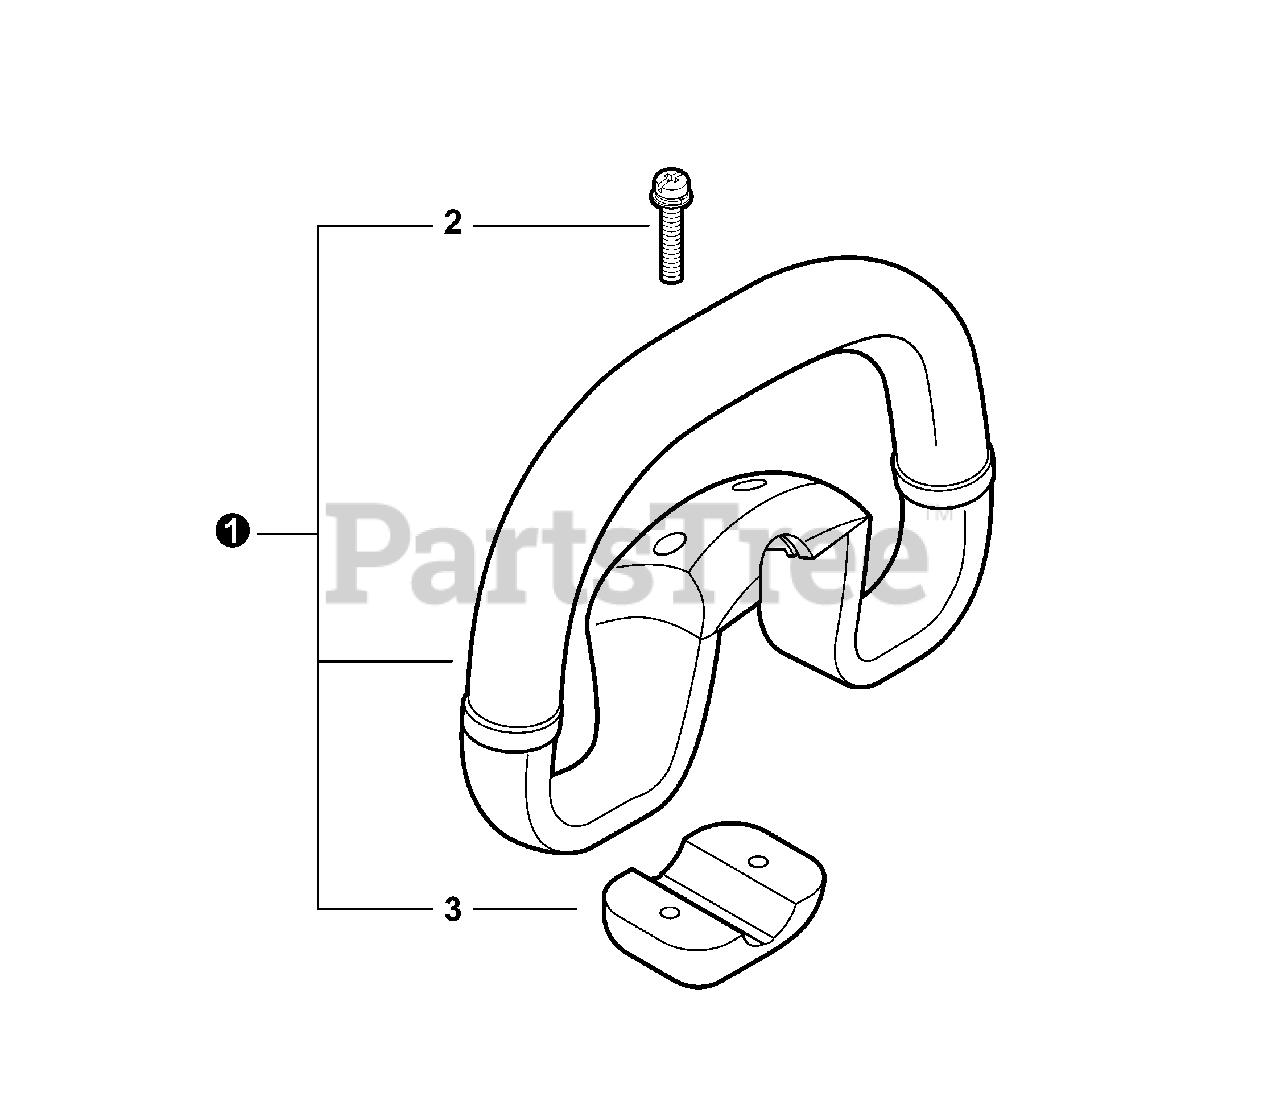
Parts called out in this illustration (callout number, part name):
1	FRONT HANDLE KIT
2	SCREW - 5×40
3	FIXTURE, HANDLE
